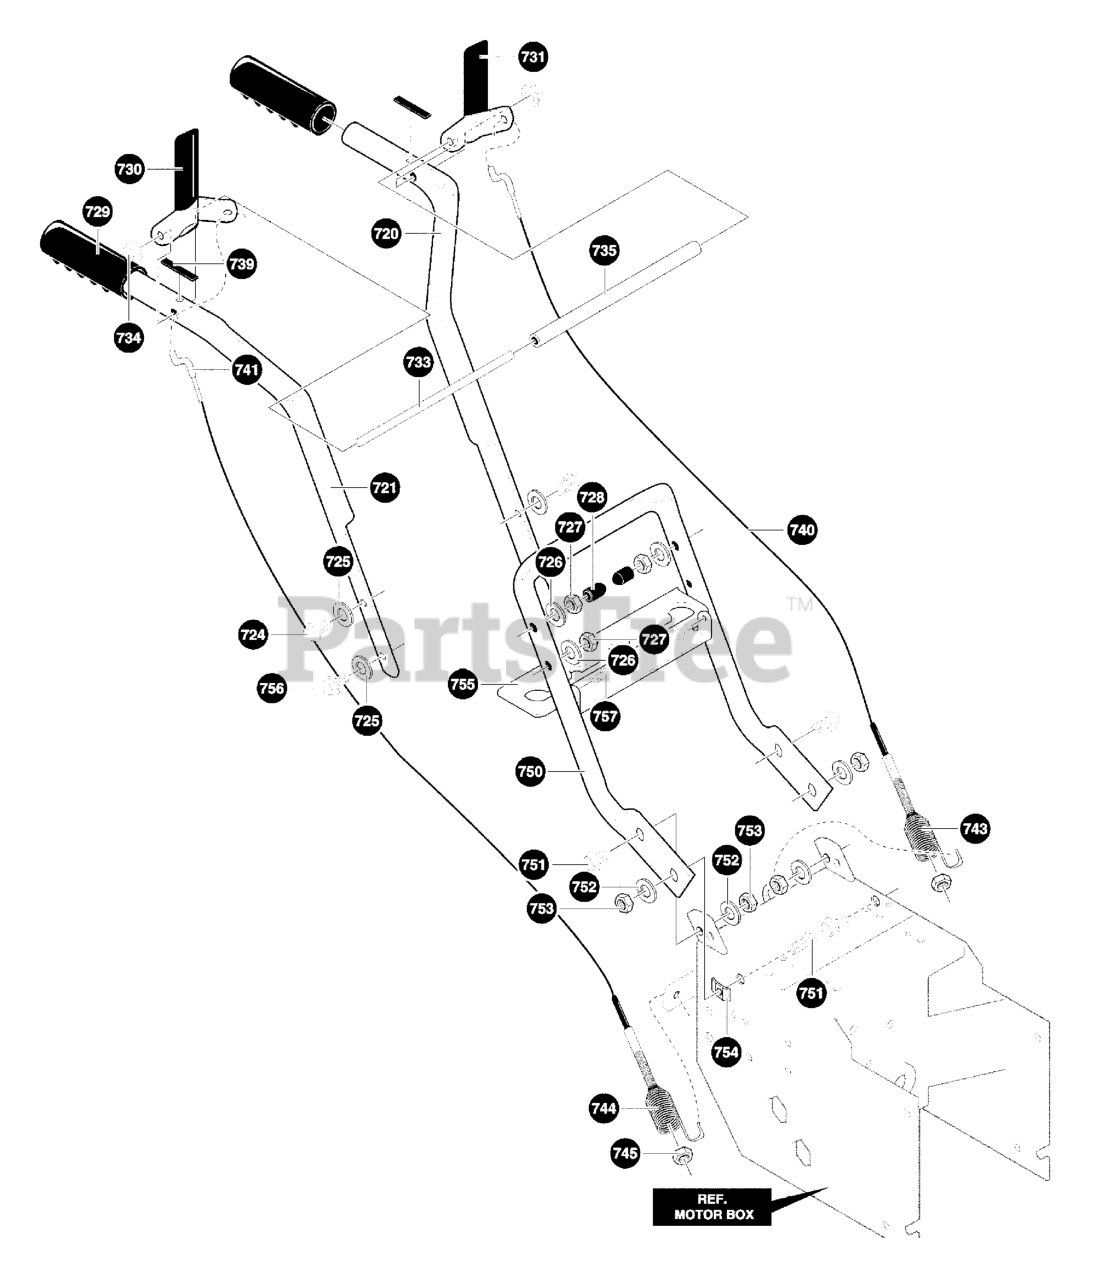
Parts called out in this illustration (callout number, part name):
720	HANDLE, UPPER LH
721	HANDLE, UPPER RH
724	SCREW
725	WASHER, FLAT
726	WASHER, .31X.58X.08
727	NUT, 5/16-18 REGHEX
728	STOP, RED PLASTIC
729	GRIP-HANDLE FINGER
730	LEVER, ASSY CLUTCH DRIVE RH
731	LEVER, ASSY CLUTCH DRIVE LH
733	ROD, PIVOT CLUTCH
734	NUT, PUSH 1/4" HEAVY DUTY
735	SPACER - HANDLE
739	BUMPER, RECTANGLE
740	CABLE, CLUTCH
741	CABLE, AUGER CLUTCH 25.5"
743	SPRING, TENSION
744	SPRING, AUGER CLUTCH
745	NUT, HEX
750	HANDLE, LOWER
751	CAPSCREW, Hex Head, 5/16-18 x 1
752	WASHER
753	NUT, HEX
754	PUSHNUT, 5/16
755	BRACKET, GEAR SEL.
